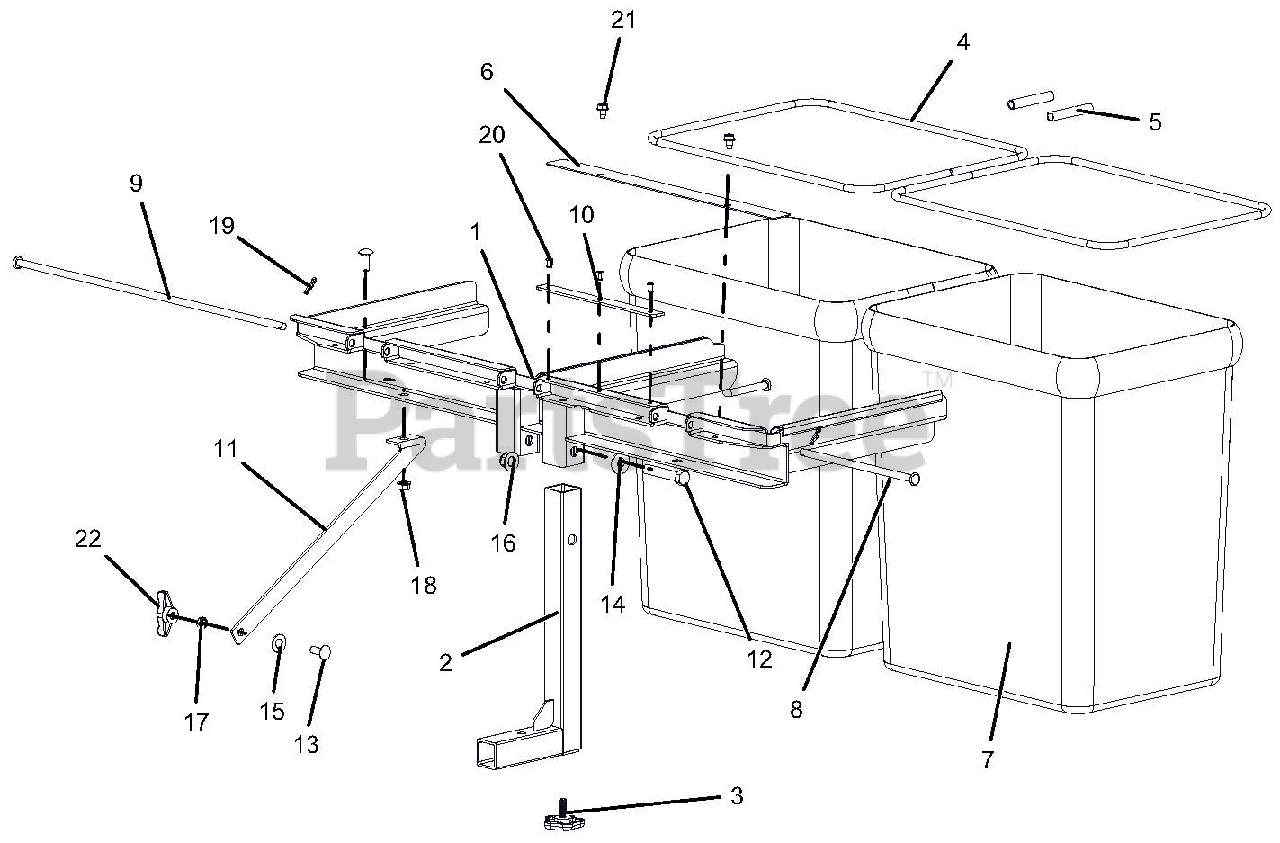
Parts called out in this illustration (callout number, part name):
1	ASS'Y, BAGGER FRAME UPPER
2	WLDMT, BAGGER MOUNT POST(2BKT)
3	KNOB, WING STUDDED
4	FRAME, ZOOM BAG
5	HOSE, .38 X.50 X 3.00 VINYL
6	BRKT-BAGGER OVERLAP
7	BAG, MESH ZOOM
8	PIN, BAGGER HINGE (L)
9	PIN, BAGGER HINGE (R)
10	SEAL, HINGE
11	STRAP, SUPPORT (BAGGER)
12	BLT-HEX .50-13X2.75 YZ GR8
13	BLT-RDHDSHSQNK.38-16X1.0 G5YZ
14	WSHR-FL-STL .531X1.250X.10 YWZ
15	WSHR-FL-STL .505X1.00X.062YWZC
16	NUT-LK-NYL-FLG .50-13 YWZC
17	NUT-HEX-JAM .375-16 YWZC
18	NUT-LK-TOP-FLG .38-16 YWZC
19	PIN-HAIR, ENDRIES #25 YWZC
20	RVT-POP.187X.527 DOME ST
21	SCR-TAP .31-18X.50 HWH TR YWZ
22	KNOB,WING .38-16 UNC NYL/TALC
